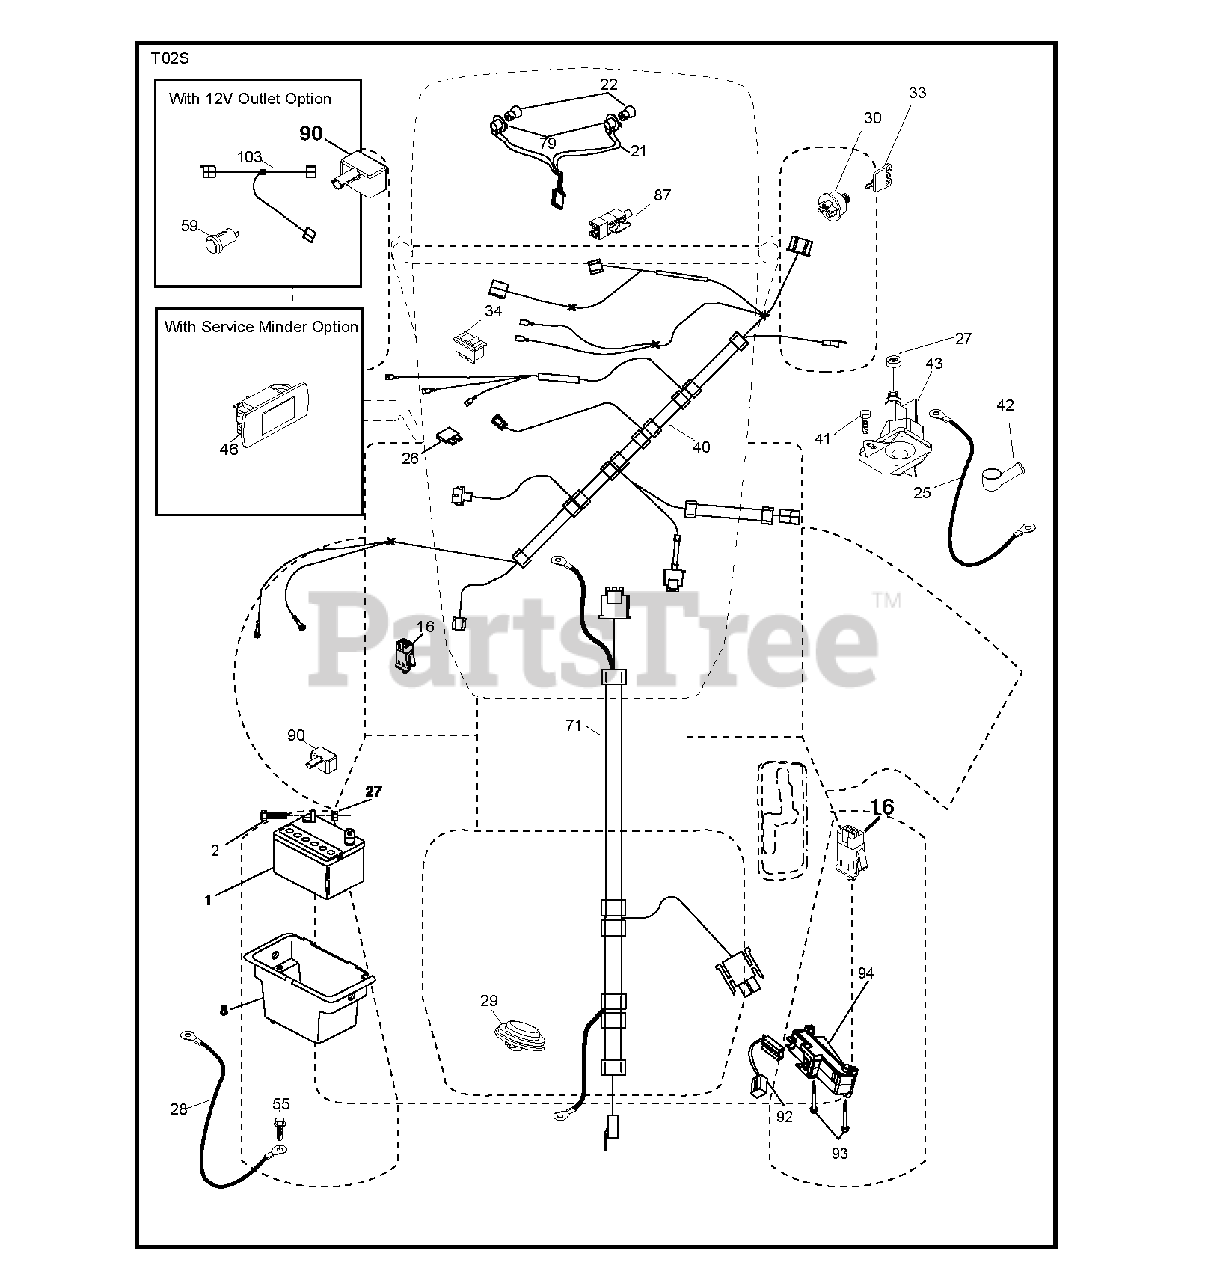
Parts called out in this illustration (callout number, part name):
1	REPL BY 532 12 38-99
8	BOX.BATTERY.MNT.REAR.L
16	SWITCH INTERLOOK PUSH-IN
21	HARNESS.LIGHT W/4152J BULBS
22	LIGHTBULB
25	CABLE.STARTER.6GA.BL/RED.14.
26	FUSE 20AMP
27	NUT
28	CABLE.BLACK.18"REAR.BA
29	SWITCH.SEAT.DELTA.OPC.
30	SWITCH.IGN.DELTA.W.LGH.ROS
33	KEY.CHAIN.BLISTER.PACK.GEN.USA
34	SWITCH LT
40	HARNESS IGN. DASH
41	SCREW
42	TERMINAL COVER
43	SOLENOID.W/BRASS.PLUNG
55	SCREW 5/16"
71	HARNESS.IGN.CHASS.TEX.REAR.BAT
79	BULB HOLDER ASM.
87	SWITCH.INTRLCK.CLUTCH.
90	COVER, TERMINAL BATTERY
92	HARNESS.PIGTAIL.CONSLE
93	SCREW.PLASTITE
94	MODULE.REVERSE.ROS
